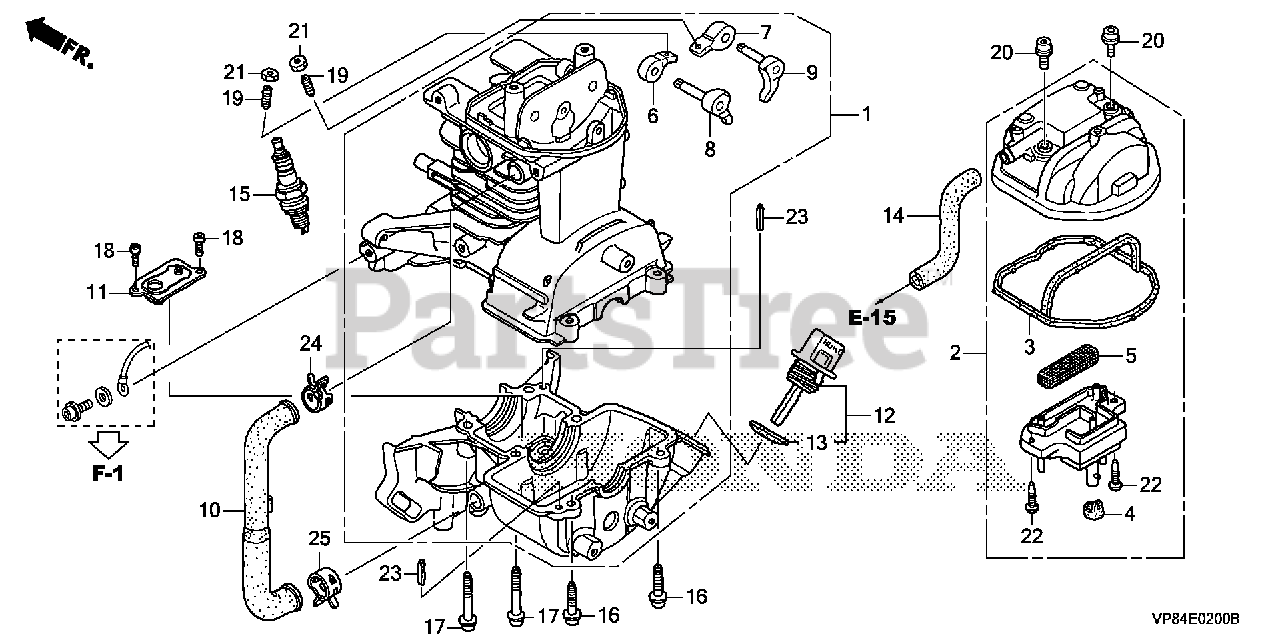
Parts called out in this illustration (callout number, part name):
1	CRANKCASE SET
2	COVER, CYLINDER HEAD
3	SEAL, HEAD COVER
4	GROMMET, HEAD COVER
5	FILTER, BREATHER
6	ARM, IN. VALVE ROCKER
7	ARM, EX. VALVE ROCKER
8	LIFTER, IN. VALVE
9	LIFTER, EX. VALVE
11	PLATE ASSY., OIL OUTLET VALVE
12	CAP ASSY., OIL FILLER
13	GASKET, OIL FILLER CAP
14	TUBE, BREATHER
15	SPARK PLUG (CMR4H) (NGK)
15	SPARK PLUG (CMR5H) (NGK)
15	SPARK PLUG (CMR6H) (NGK)
16	BOLT, SOCKET (5X20)
17	BOLT, SOCKET (5X30)
17	BOLT, SOCKET (5X32)
18	SCREW, PAN (4X8)
19	SCREW, TAPPET ADJUSTING
20	BOLT, SOCKET (5X12)
21	NUT, TAPPET ADJUSTING
22	SCREW, TAPPING (4X12)
23	PIN, SPRING (4X10)
24	CLAMP, TUBE (D12)
25	CLAMP, TUBE (D13)
